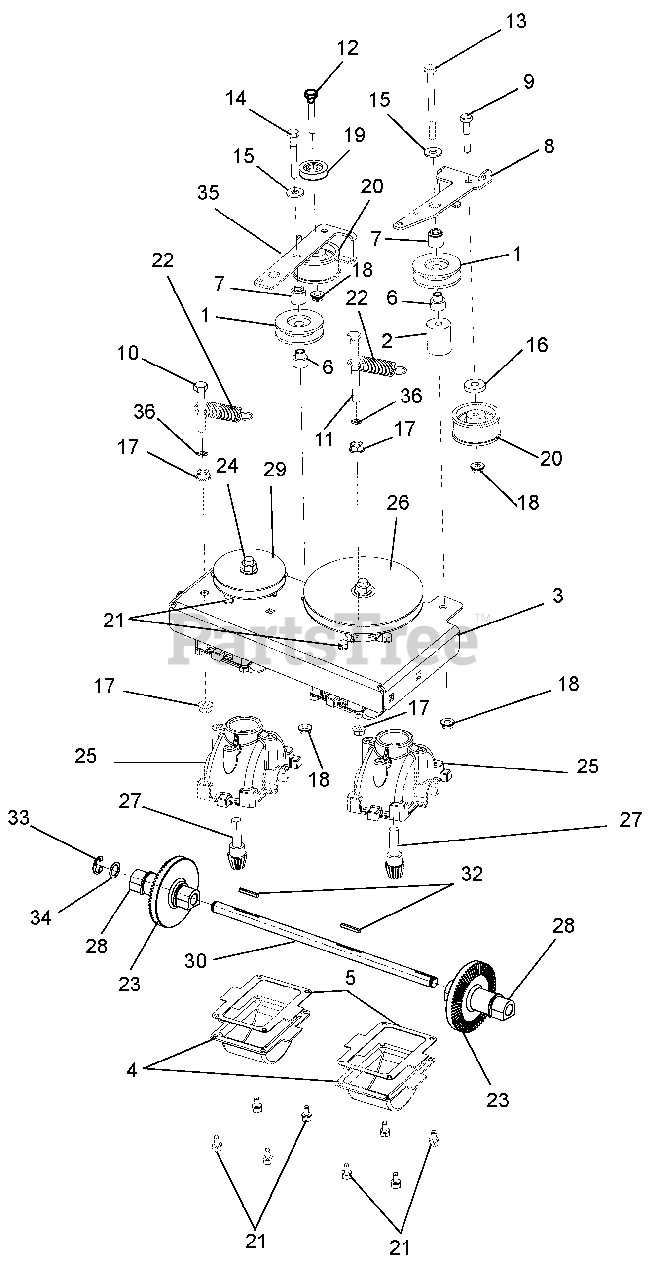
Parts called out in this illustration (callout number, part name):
1	Idler, 3L Front Side .38 x 1.875
2	Spacer, Reverse Idler
3	Plate, Transmission Mount
4	Sump, Gearbox
5	Gasket, Transmission
6	Spacer, Idler Pulley
7	Spacer .390 x .75 x .189
8	Bracket, Transmission Idler Arm
9	Bolt, Hex .25-20 x 1.50
10	Bolt, Hex .31-18 x 2.00
11	Bolt, Hex .31-18 x 3.50 Grade 5
12	Bolt, Hex .25-20 x 1.75
13	Bolt, Hex .25-20 x 3.25
14	Bolt, Hex .25-20 x 2.00
15	Washer, Flat Steel .312 x .734 x .065
16	Washer, Flat Steel .38 x .87 x .179
17	Nut, Spin Lock Flange .312-18
18	Nut, Locking Top Flange .25-20
19	Pulley, Cable
20	Pulley, Idler .25 x 1.87 x .97
21	Screw, Tapping 10-24 x .375 Pre-Coat
22	Spring, Tension .063 x .625 x 2.50
23	Gear, Bevel
24	Nut, Top-Locking Flange .38-16
25	Housing, WAW Gearbox
26	Pulley, Reverse Input
27	Pinion, Gearbox Input
28	Bushing, Transmission Output Shaft
29	Pulley, Transmission Input
30	Shaft, Transmission Output
31	Kit, WAW Transmission Shaft (includes 30, 32, 33 and 34)
32	Key, 1/8 x 1/8 x 1.0
33	Ring, Retaining - External .500 x .042
34	Washer, .500 x .750 x .020 Thrust
35	Arm, Forward Idler
36	Nut, Push .312
